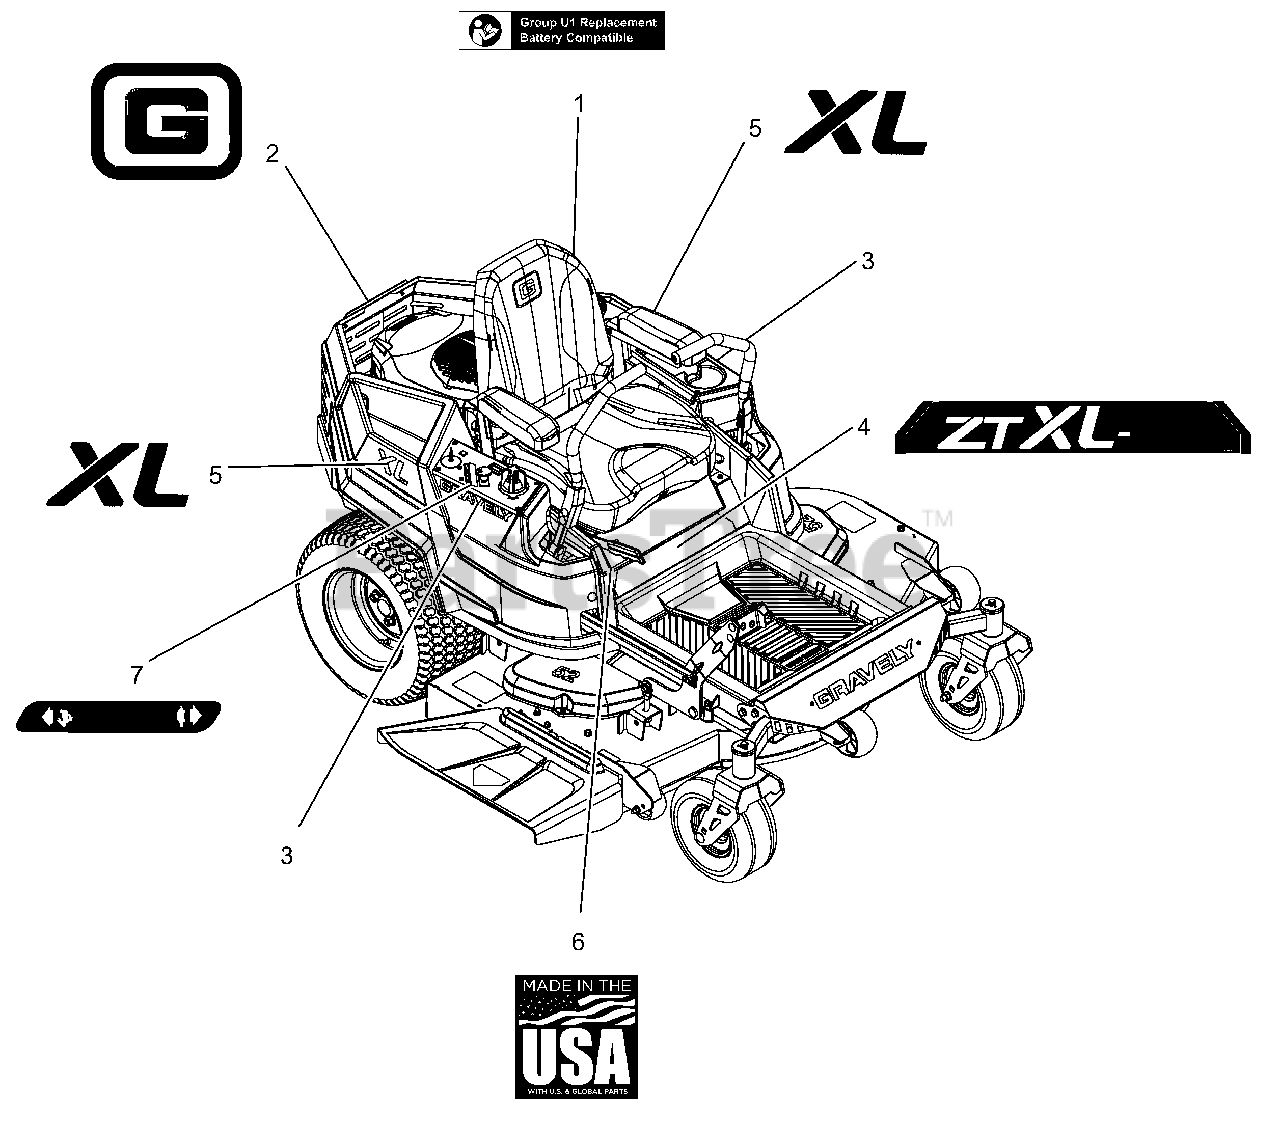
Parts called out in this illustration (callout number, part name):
1	DECAL, U1 BATTERY REPLACEMENT
2	DECAL, GRAVELY BRAND
3	DECAL, 9.5" GRAVELY LOGO
4	DECAL, ZT XL 52"
5	DECAL, "XL"
6	DECAL, MADE IN USA
7	DECAL, DASH DECAL
